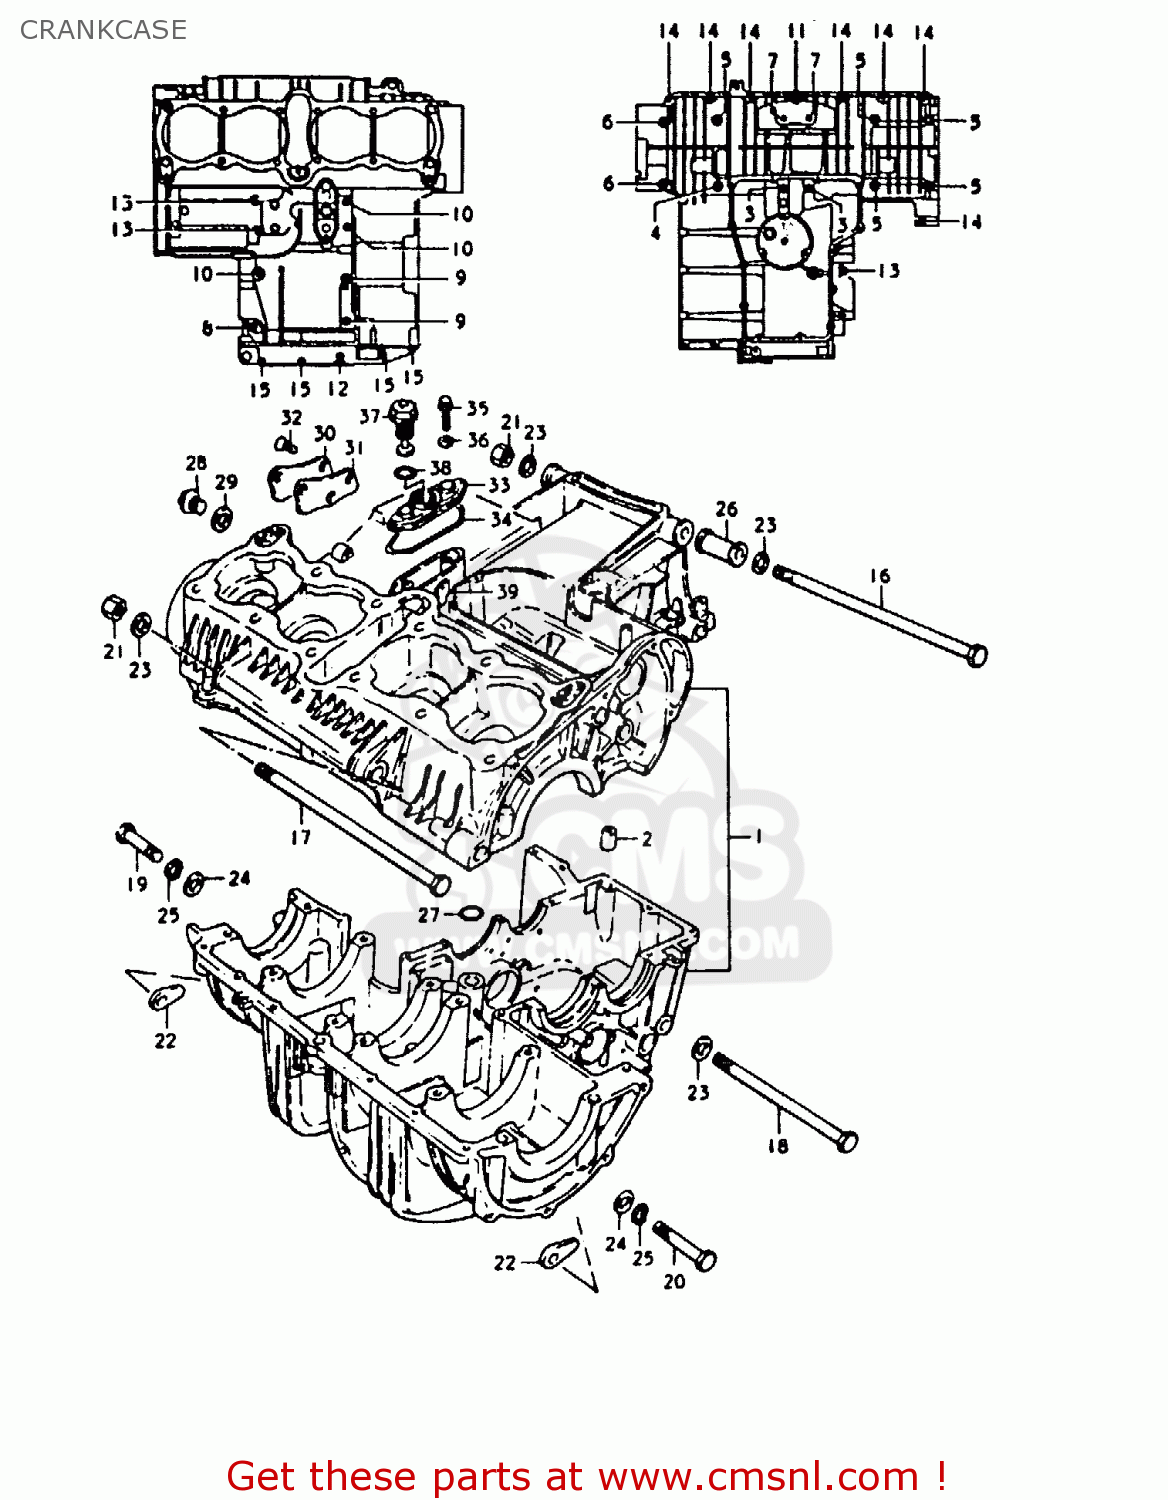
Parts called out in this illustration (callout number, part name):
1	CRANKCASE SET
2	PIN
3	BOLT
4	BOLT
5	BOLT 8X90
6	BOLT 8X65
7	BOLT
8	BOLT
9	BOLT
10	BOLT (6X75)
11	BOLT ,6X50
12	BOLT,UNDER
13	BOLT
14	BOLT 6X35
15	BOLT
16	BOLT 10X265
17	BOLT 10X250
18	BOLT(10X165)
19	BOLT 10X60
20	BOLT (10X50)
21	NUT
22	NUT
23	WASHER
24	WASHER(10.5X20X3.2)
25	LOCK WASHER
26	SPACER,ENGINE MOUNT
27	O RING(D:3.2,ID:12.9)
28	PLUG (14X12)
29	GASKET(14X19.2X2) (NAS)
30	CAP,OIL GALLERY
31	GASKET,OIL GALLERY (MCA)
32	SCREW
33	HOUSING,OIL PRESSURE SWITCH
34	O RING,PRESSURE SWITCH HOUSING
35	BOLT
36	GASKET (NAS)
37	SWITCH ASSEMBLY
38	O RING(D:1.9,ID:18.8)
39	GROMMET,STARTING MOTOR
